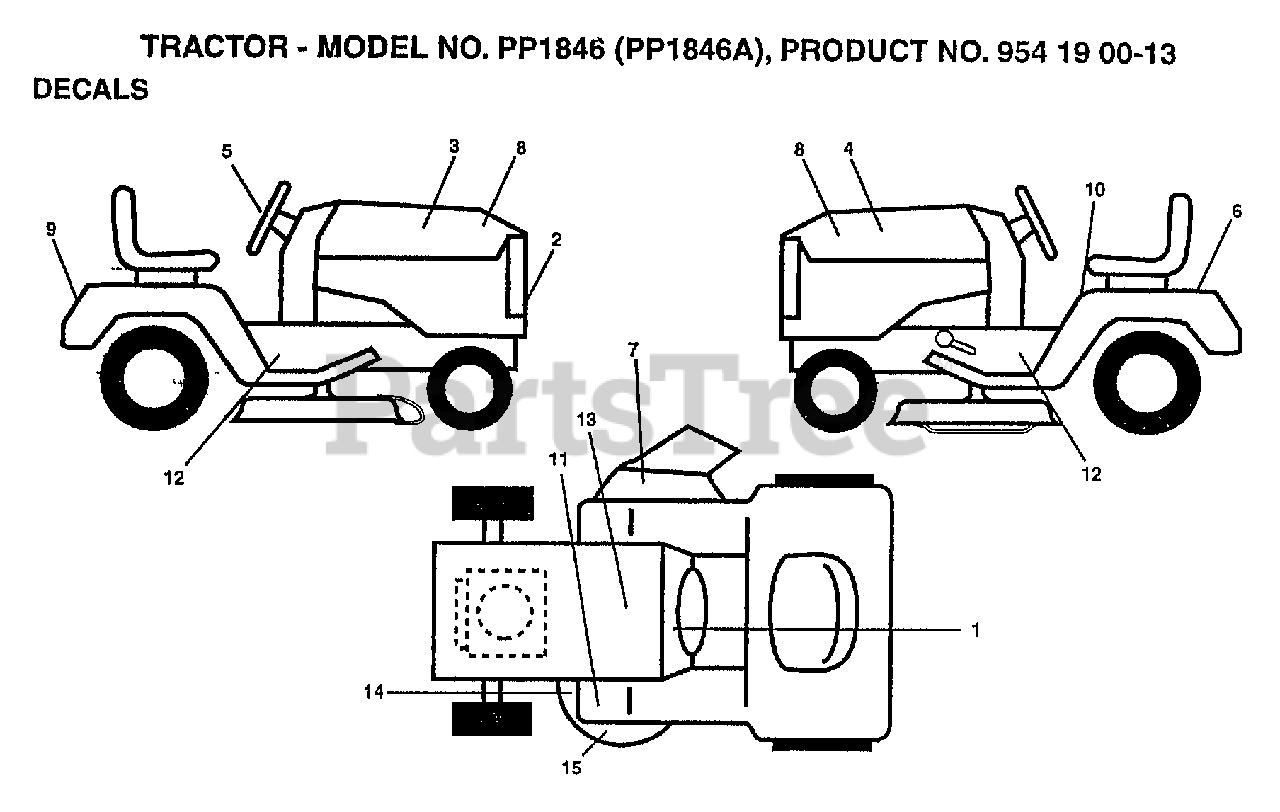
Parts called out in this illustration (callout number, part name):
1	DECAL.INSTR.FRENC
2	DECAL, GRILLE
3	"DECAL HOOD,RH"
4	"DECAL HOOD, LH"
5	DECAL, SCL COLD START HYD
6	RETAINER-SPRING
7	"DECAL, WARNING"
8	DECAL DOMED
9	DECAL, FENDER
10	DECAL.CAUT.ENG/FR
11	DECAL T
12	"DECAL CHASSIS,46"
13	DECAL.BATRY.3-3908
14	"DECAL.V.BELT.44"""
15	"DECAL,ENVIRO DECK"
